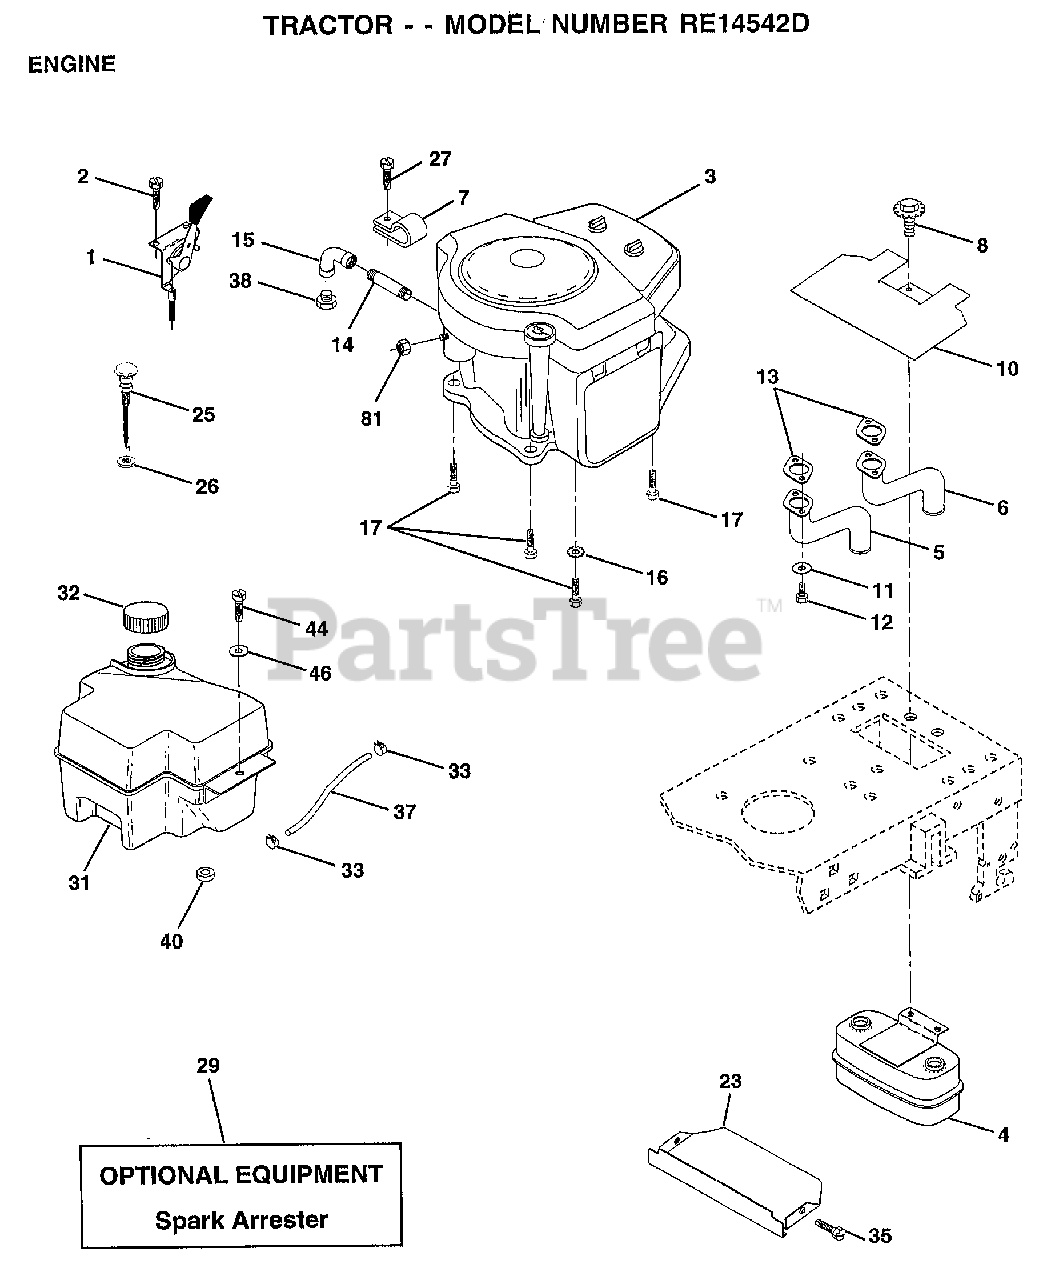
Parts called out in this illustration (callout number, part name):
1	CONTROL THRT 35.5
2	SCREW LT
4	MUFFLER.TW.LOTONE
5	EXHAUST.B&S.18.LH
6	EXHAUST.B&S.18.RH
7	CLAMP.TUBE.DBL.EN
8	BOLT.5/16-18.UNC
10	SHIELD.HEAT.
11	LOCKWASHER
13	GASKET MUFFLER
14	PIPE NIPPLE LT
15	ELBOW
16	LOCKWASHER
17	SCREW LT
23	SHIELD.BRN/DBR.GD
25	CONTROL.CHOKE.37
26	"NUT,KEPS 3/8-24IM"
27	"SCREW-TT,10-32 FL"
31	TANK.FUEL.FRONT.
32	CAP ASM FUEL
33	HOSE CLAMP
35	SCREW
37	LINE FUEL
44	SCREW HEX CRT
46	WASHER
81	NUT
